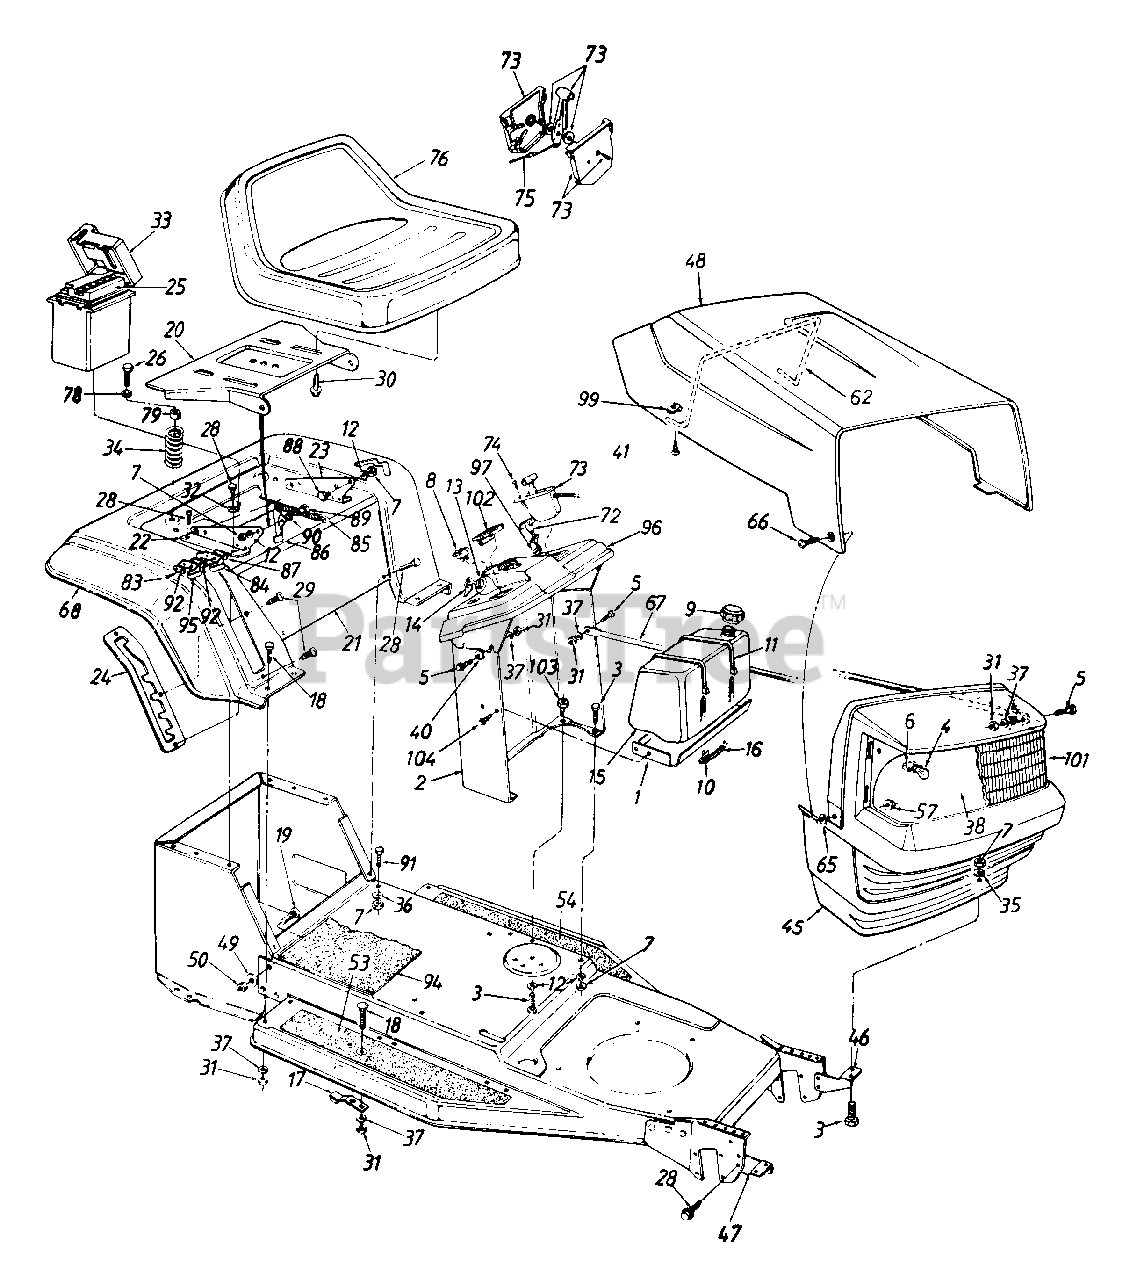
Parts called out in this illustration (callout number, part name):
3	Hex Bolt 5/16-18 x .75" Lg.
4	Bulb
5	Hex Bolt 1/4-20 x .62" Lg.
6	Socket
7	Hex Nut 5/16-18 Thd.
8	Light Switch
9	Gas Cap
10	Hose Clamp
11	Cable Tie
12	L-Wash. 5/16" I.D.
13	Ignition Switch
14	Ignition Key
15	Fuel Tank
16	Gas Line 15" Long
17	Blade Brake Ass'y.
18	Carriage Bolt 1/4-20 x .62"
19	Ribbed Neck Bolt 3/8-24 x .8"
20	Seat Pivot Brkt.
25	Battery
26	Hex Self-Tap Screw 5/6-18 x 1.25" Lg.
28	Hex AB-Tap Scr. 5/16 x .75" Lg.
29	Torx Mach. AB-Tap Scr. 1/4 x .62" Lg.
30	Hex Self-Tap Scr. 3/8-16 x .75" Lg.
31	Hex Nut 1/4-20 Thd.
32	External L-Wash. 5/16" I.D.
33	Battery Box w/Cover
34	Compression Spring
35	Fl-Wash..34" I.D. x .68" O.D.
36	Bell-Wash. 5/16" I.D.
37	L-Wash. 1/4" I.D.
38	Grille Reflector Label
40	Bell-Wash..265" I.D. x.75"
41	Pan Hd. Scr. 10-24 x .75" Lg.
45	Grille
46	Grille Mtg. Brkt.- L.H.
47	Grille Mt .Brkt.- R.H.
50	Hex L-Nut 3/8-24 Thd
53	Foot Pad - R H
54	Foot Pad - L H
57	Lock Nut 1/4-28 Thd.
62	Hood Spring
65	Fl-Wash 28" I.D. x 75" O.D.
66	Shld Bolt
72	Choke Control
73	Throttle Control Box
74	Truss AB-Tap Scr #10 x 5"
75	Throttle Wire (B&S)
76	Seat Assembly (Low Back)
78	Fl-Wash 344" I.D x 88" O.D.
79	Bushing
83	Hex Tap Scr #8 x 5" Lg
84	Safety Switch (Seat)
85	Ext Spring 5.31" Lg
86	Seat Lift Brkt.
87	insulator Boss Plate
88	Shld. Bolt 437" Dia x 162" Lg.
89	Shld. Bolt 437" Dia. x 268" Lg
90	Spr. Wash. 445" I.D. x 75" O.D.
91	Hex Wash Hd. Scr. 5/16-18 x .62" Lg.
92	Insulator Plate
94	Center Foot Pad
95	Safety Switch (Seat)
96	Dash Panel
97	Retainer Clip
99	Speed Nut
101	Lens
103	Hex Jam Nut 5/16-18 Thd.
104	Hex Wash. Hd. Tap Scr 1/4-20 x .5" Lg.
